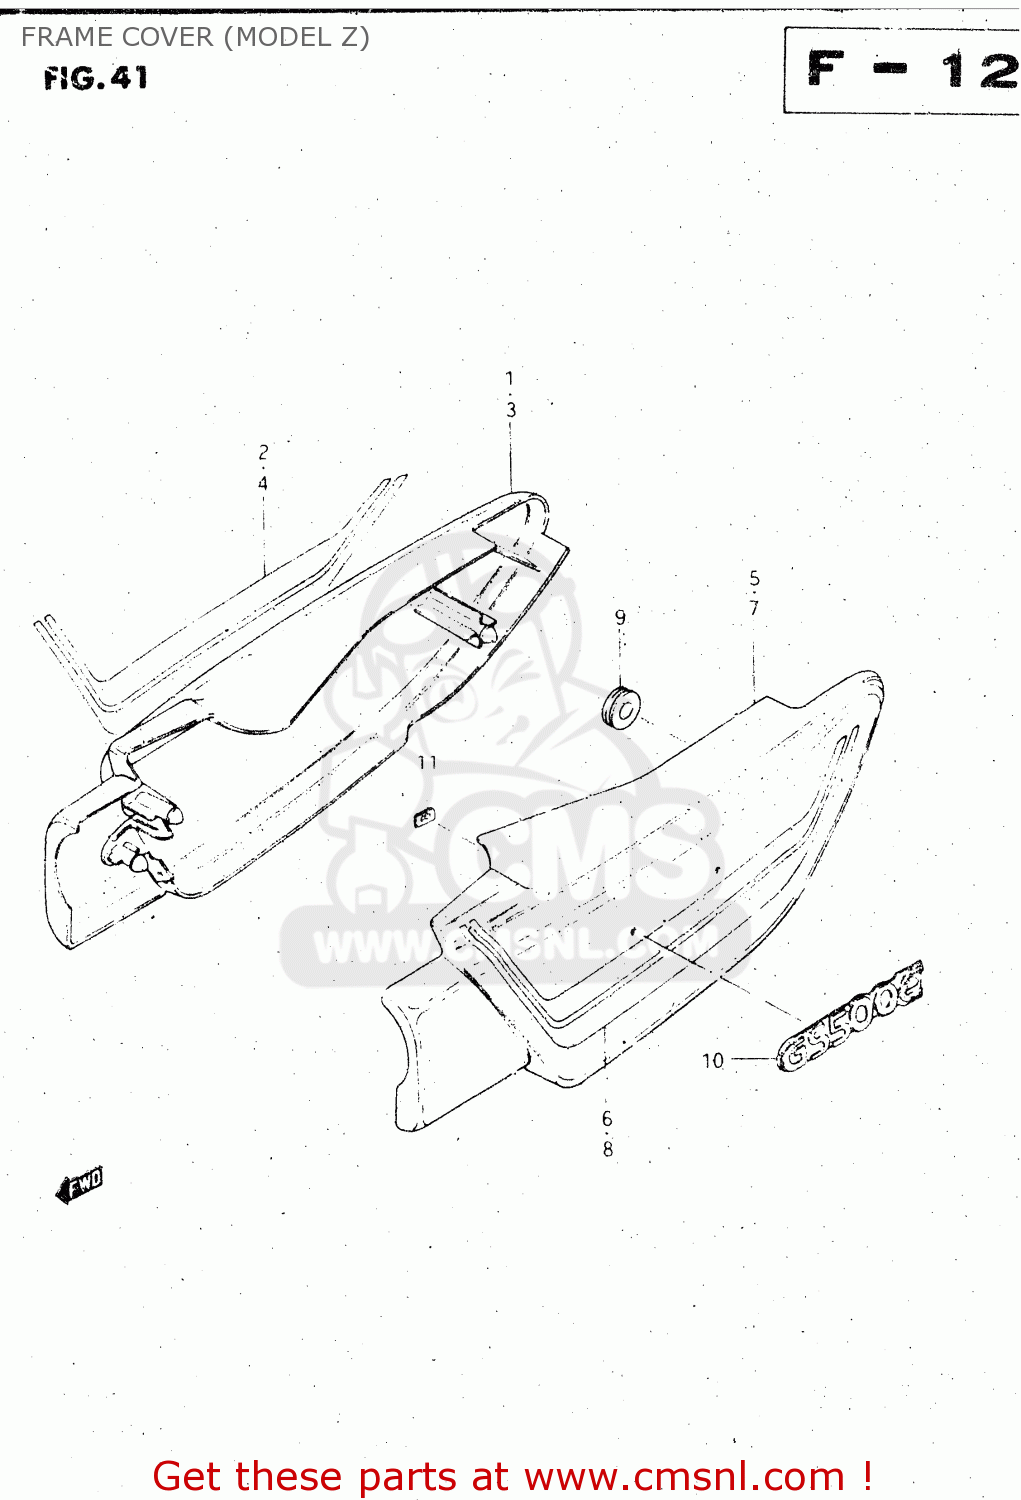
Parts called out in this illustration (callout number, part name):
1	COVER,FRAME,RIGHT
2	TAPE, RH
3	COVER, FRAME RH (BLUE)
4	TAPE, RH
5	COVER,FRAME,LEFT
6	TAPE, LH
7	COVER, FRAME LH (BLUE)
8	TAPE, LH
9	CUSHION
10	EMBLEM
11	NUT
